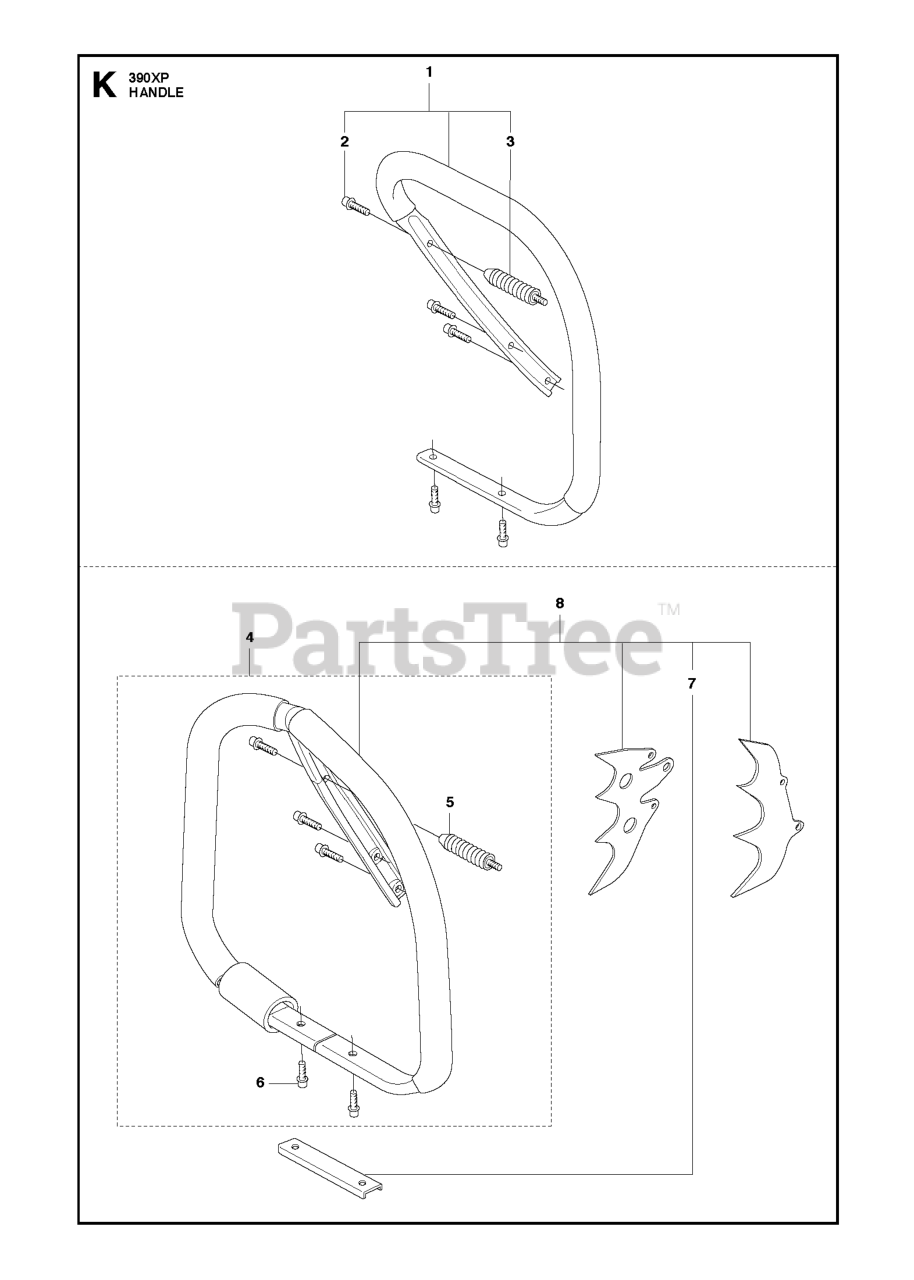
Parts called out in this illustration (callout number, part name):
1	FRONT HANDLE
2	SCREW ITXSCFT
4	HANDLE
5	SPRING
5	VIBRATION ABSORBER
6	SCREW ITXSCFT
7	PLATE
8	390XP WRAP KIT
